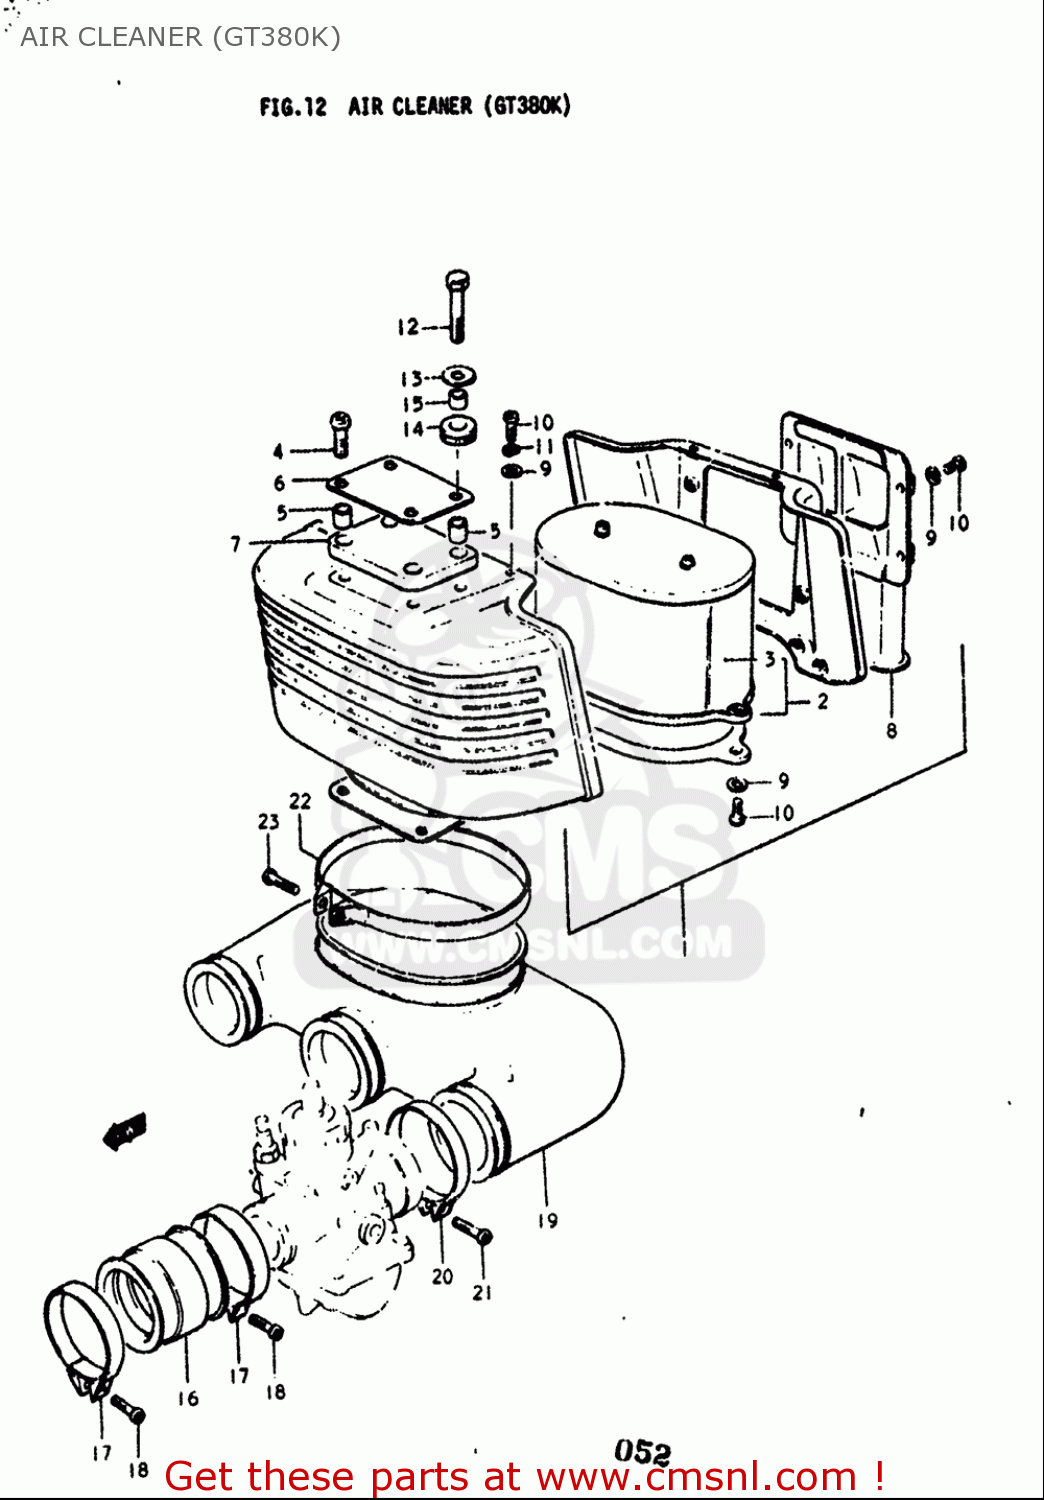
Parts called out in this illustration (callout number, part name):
4	SCREW
9	WASHER
10	SCREW
11	WASHER,LOCK
12	BOLT
13	WASHER(6.5X20X1.2)
14	CUSHION
15	SPACER,6.5X9X7
17	CLAMP
18	SCREW
20	CLAMP
21	SCREW
22	CLAMP
